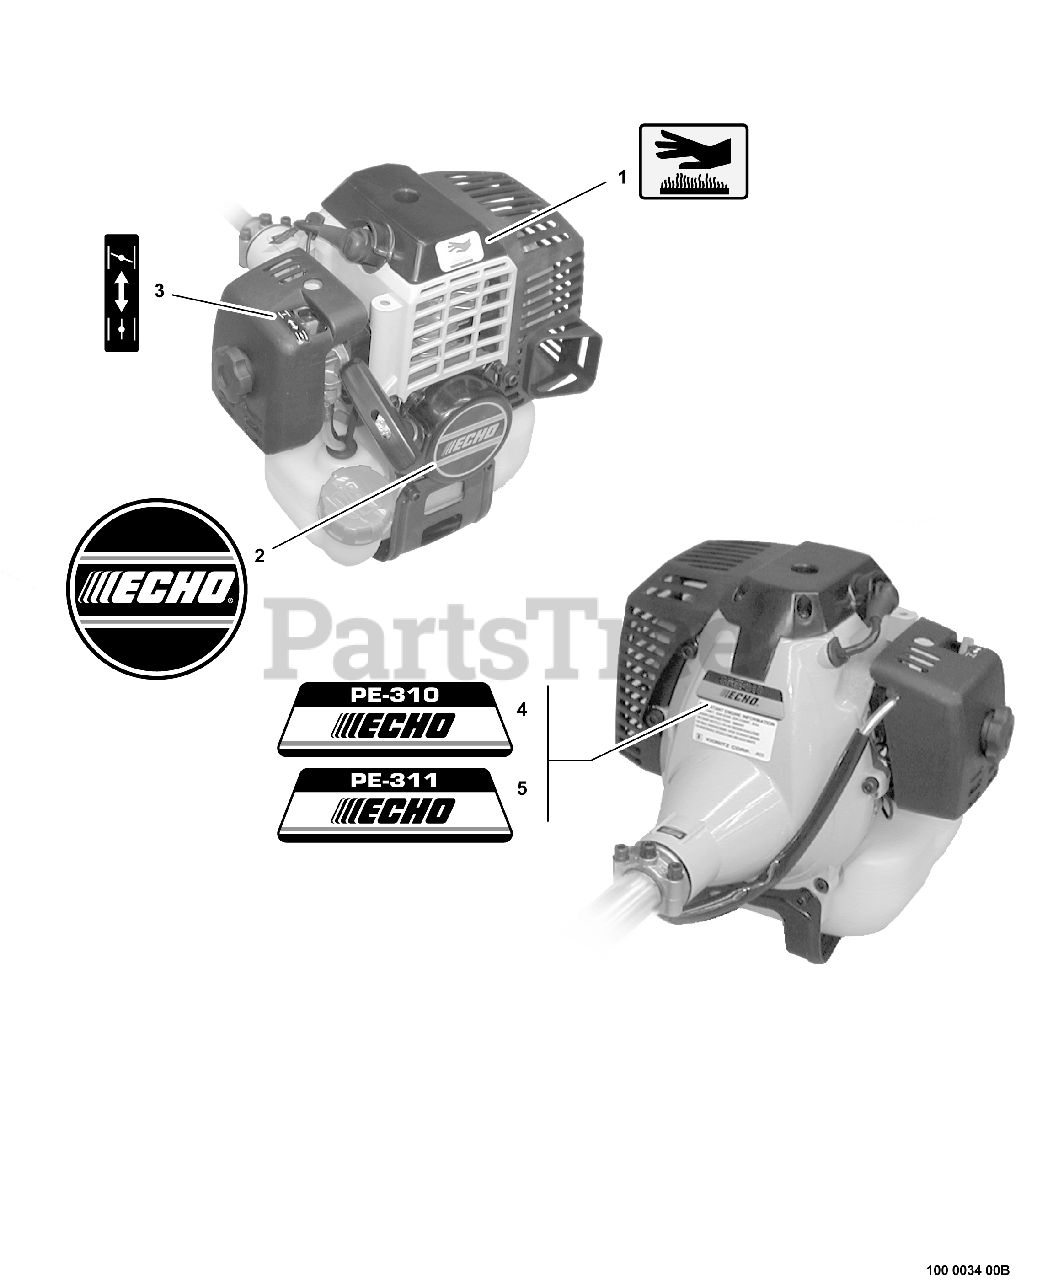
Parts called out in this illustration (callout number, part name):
1	LABEL - HOT SURFACE
2	LABEL - ECHO
3	LABEL - CHOKE
4	LABEL - MODEL PE-310
5	LABEL - MODEL PE-311
